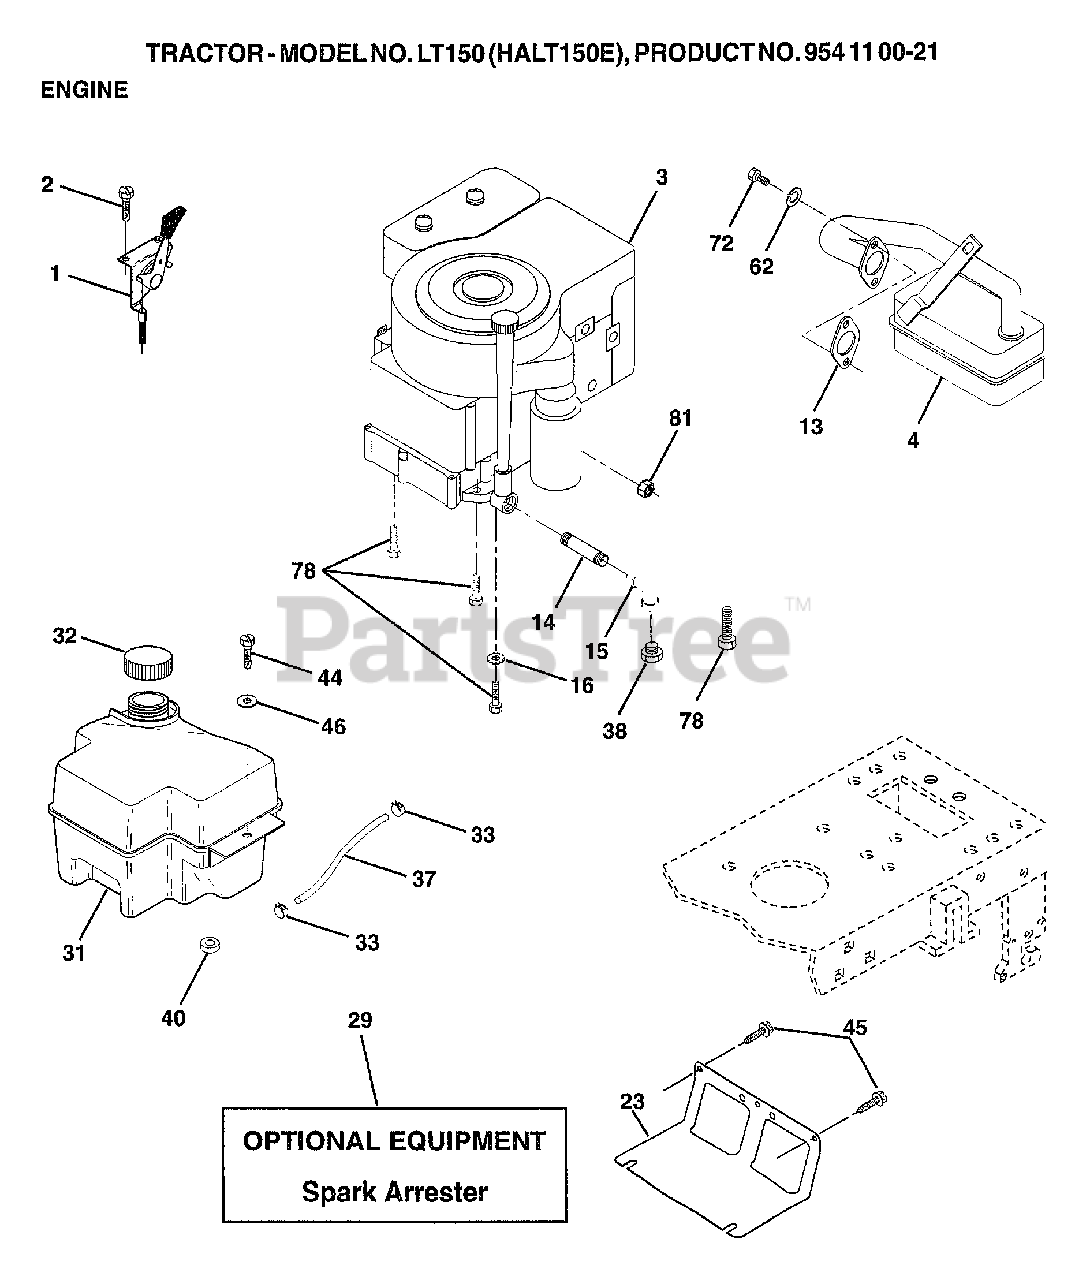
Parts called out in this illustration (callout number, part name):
2	SCREW HEX THD CUT 1/4-20X5/8 T
14	NIPPLE PIPE 3/8 NPT X 3"
15	ELBOW STD 90 DEGREE 3/8-18 NPT
16	WASHER LOCK
23	SHIELD BRN/DBR GUARD
29	KIT.ARREST.SPARK (392-390)
46	WASHER 9/32 X 7/8 X 16 GA
62	WASHER, LOCK
72	SCREW HEXHD CAP 5/16-18X3/4
81	LOCKNUT
